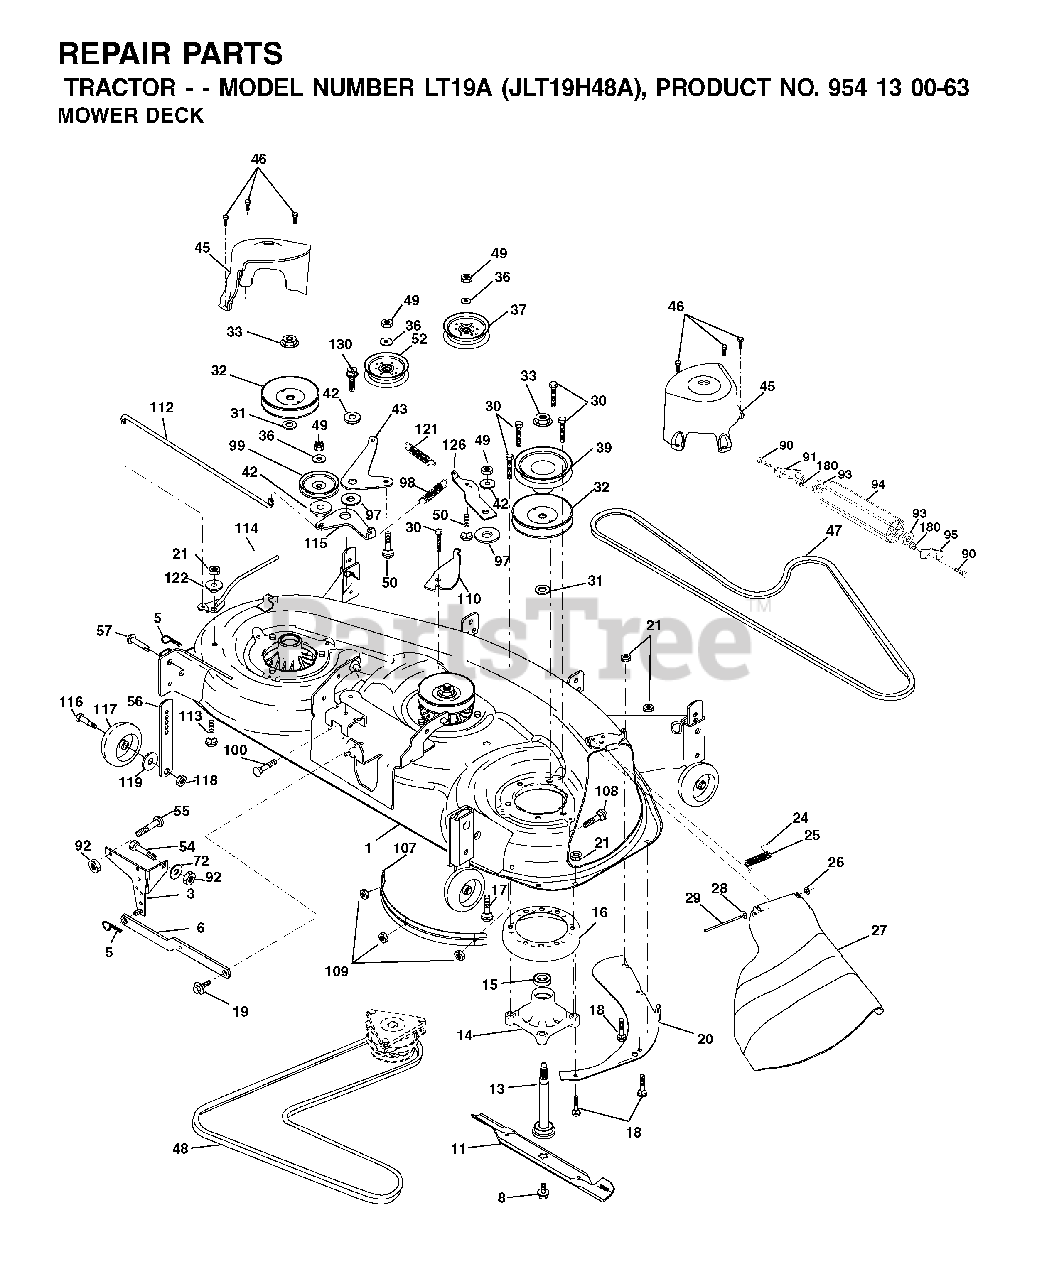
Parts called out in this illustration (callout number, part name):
1	DECK, WELDMENT MWR 48"
3	BRKT ASM SWAY BAR
5	RETAINER-SPRNG RB
6	REAR SUSP ARM
8	BOLT 7/16 ASM BLADE
11	BLADE
13	SHAFT ASM W/LOWER BEARING
14	HOUSING, MANDREL 48"
16	STRIPPER, MWR ROUND
17	BOLT
18	BOLT
19	BOLT SHD 5/16-18
20	BAFFLE, VORTEX MWR
21	LOCKNUT
24	CAP-SLEEVE LT
25	SPRING, TORSION
26	NUT PUSH M
27	SHIELD, DEFLECTOR MOWER
28	WASHER
29	ROD.HINGE
30	SCREW, WASHER HEAD
31	WASHER
32	PULLEY, MANDREL
33	NUT, FLG TOPLOCK 9/16"
37	PULLEY, IDLER, FLAT
39	PULLEY.IDLER.DRIVEN
42	SPACER.RETAINER.MOWER
43	ARM, IDLER SECONDARY
45	COVER, MANDREL DECK
46	SCREW.1/4-20X5/8
47	V-BELT, MWR SECONDARY
48	V-BELT PRIMARY 48"
49	LOCKNUT
50	BOLT.3/8-16X1.50
52	PULLEY.IDLER.FLAT.46.PR.DR.
55	BOLT D
56	BAR.ADJUST.WHEEL.ANTI.SCALP.BL
57	RIVET.PIN.HEAD.YELLOW
72	WASHER
90	BOLT RB
91	BRKT ASM NOSEROLLER(L)48"
92	NUT
94	NOSE ROLLER 48"
95	BRKT, ASM NOSEROLLER(R)48
97	HARDENED WASHER
98	SPRING PRIMARY DRIVE
99	PULLEY,IDLER"V"
100	BOLT
107	BAFFLE VAC EDGE MWR
109	NUT.CROWNLOCK.1/4
110	ARM, SPRING SECONDARY
112	LEVER, TENSION RELIEF LINK
114	LEVER ASM, TENSION RELIEF
115	ARM, SPRING TENSION RELIEF
116	BOLT, SHOULDER
117	WHEEL. GUAGE RALLY
118	LOCKNUT
119	WASHER
121	SPRING SECONDARY DR
122	BUSHING, PIVOT TENSION RELIEF
126	ARM, IDLER PRIMARY DECK
130	SCREW 3/8-16X1
132	SCREW 3/8-16X3/4
180	NUT.71038.31-18.HEX.NYLOCK
